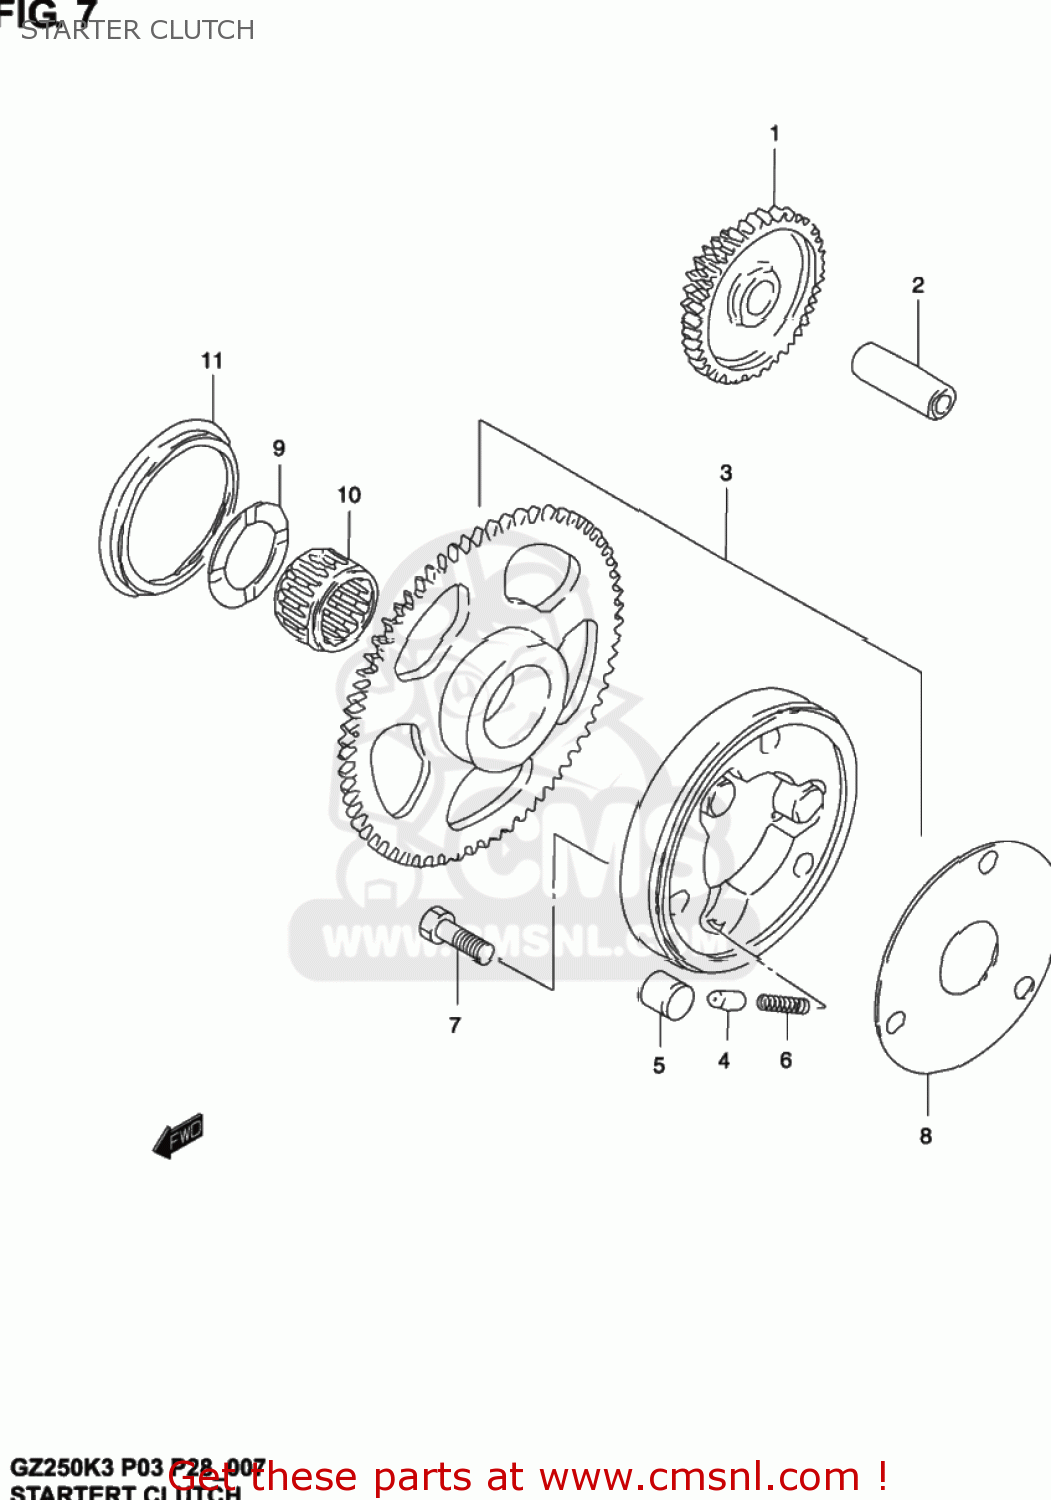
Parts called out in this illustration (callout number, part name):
1	GEAR,STARTER IDLE
2	PIN(7.4X13X40)
3	CLUTCH SET,STARTER
4	PIECE,PUSH
5	PIN(14X13)
6	SPRING
7	BOLT(8X20)
8	SHIM,STARTER CLUTCH HUB
9	WASHER(27X40X2.5)
10	BEARING(27X32X21.8)
11	SEAL,OIL(52X62X6.8)
